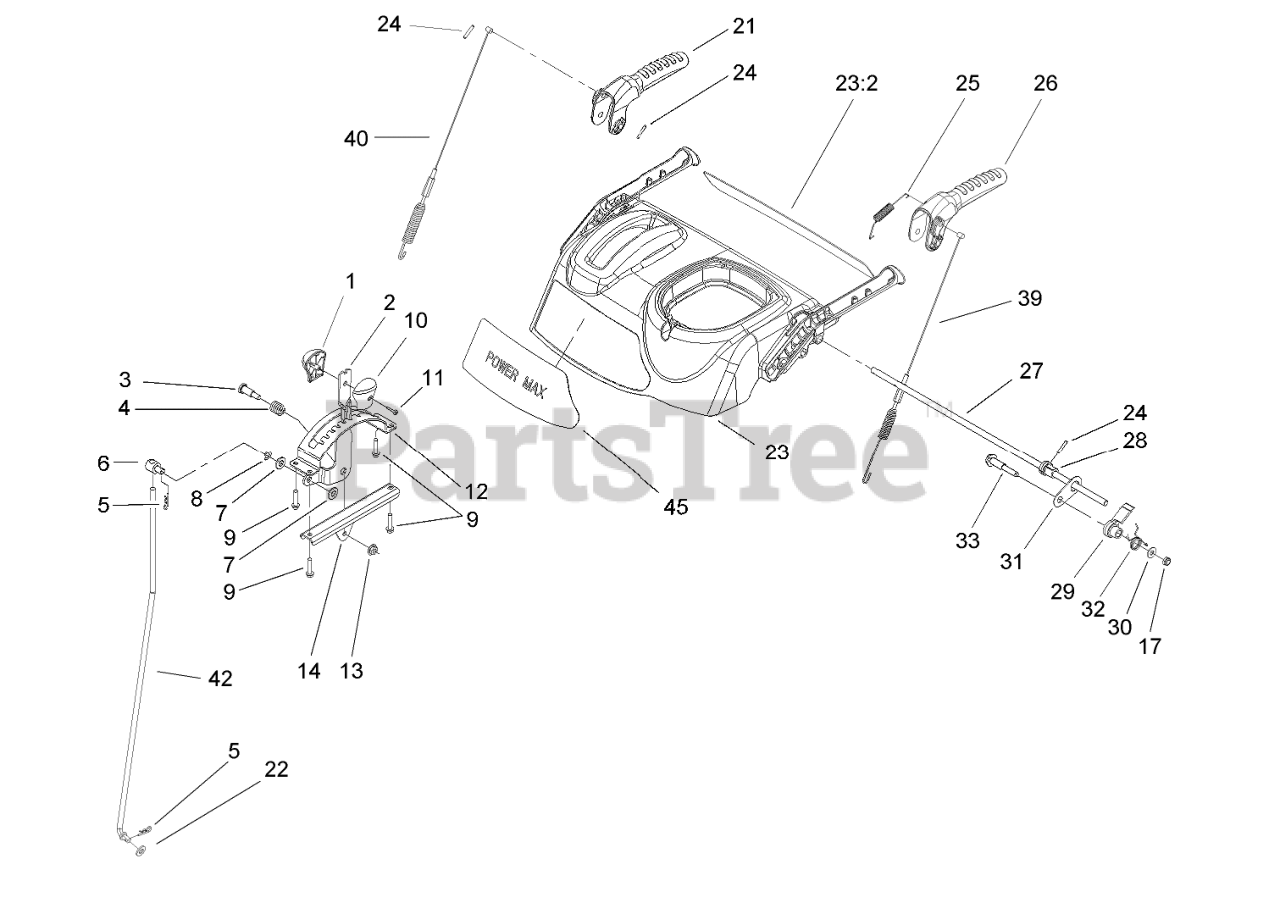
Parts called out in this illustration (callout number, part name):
1	KNOB-SHIFT, RH
2	SELECTOR-SPEED
3	SCREW-SHOULDER
4	SPRING-COMPRESSION
5	PIN-COTTER
6	TRUNNION
7	WASHER-FLAT
8	WASHER-SPRING
9	SCREW-PLASTITE
10	KNOB-SHIFT, LH
11	SCREW-PPH
12	GUIDE-SELECTOR, SPEED
13	NUT-HF
14	MOUNT-SELECTOR, SPEED
17	NUT-LOCK, NI
21	LEVER-AUGER
22	WASHER-FLAT
23	CONTROL PANEL ASM
23:2	DECAL-PANEL, BACK CONTROL
24	PIN-SPRING
25	SPRING-TENSION
26	LEVER-TRACTION
27	ROD-LOCKOUT
28	CAM-LOCKOUT
29	LATCH-LOCKOUT
30	WASHER-FLAT
31	LINK-LOCKOUT
32	SPRING-TORSION
33	SCREW-SHOULDER
39	CABLE-TRACTION
40	CABLE-AUGER
42	ROD-SHIFT
45	DECAL-PANEL, CONTROL
